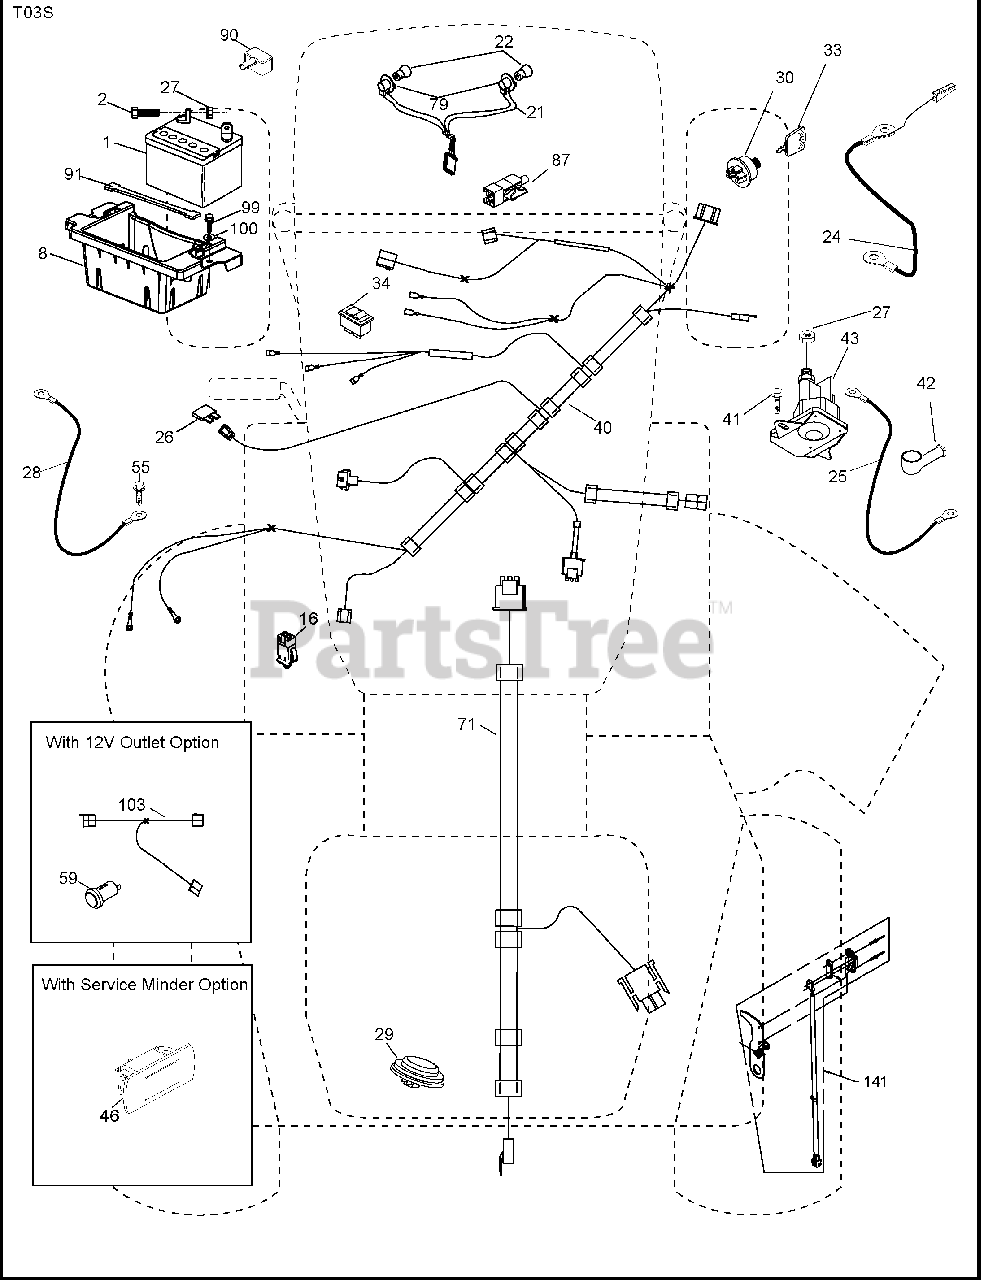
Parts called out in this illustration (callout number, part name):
1	Battery
2	Bolt Hex Head 1/4-20 x 3/4
8	Box Battery
16	Switch Interlock Push-In
21	Harness Socket Light w/4152J
22	Bulb Light
24	Cable Battery
25	Cable Starter
26	Fuse
27	Nut Keps Hex 1/4-20 unc
28	Cable, Ground
29	Switch, Seat
30	Switch, Ign
33	Key, Ignition
34	Switch Light / Reset
40	Harness Ign.
41	Screw Thd Cut 1/4-20 x 1/2
42	Cover, Terminal
43	Solenoid
46	Gauge Hourmeter
55	Screw Thdrol 5/16-18 x 3/4 TYTT
71	Harness Ign. Dash
79	Socket Asm Bulb Twistlock
87	Switch Interlock Clutch Cable
90	Cover Terminal Battery
91	Strap Battery Mount Front
99	Screw Hexwsh Thdrol 1/4-20 x 3/4
100	Washer 9/32 x 7/8 x 16 Ga.
